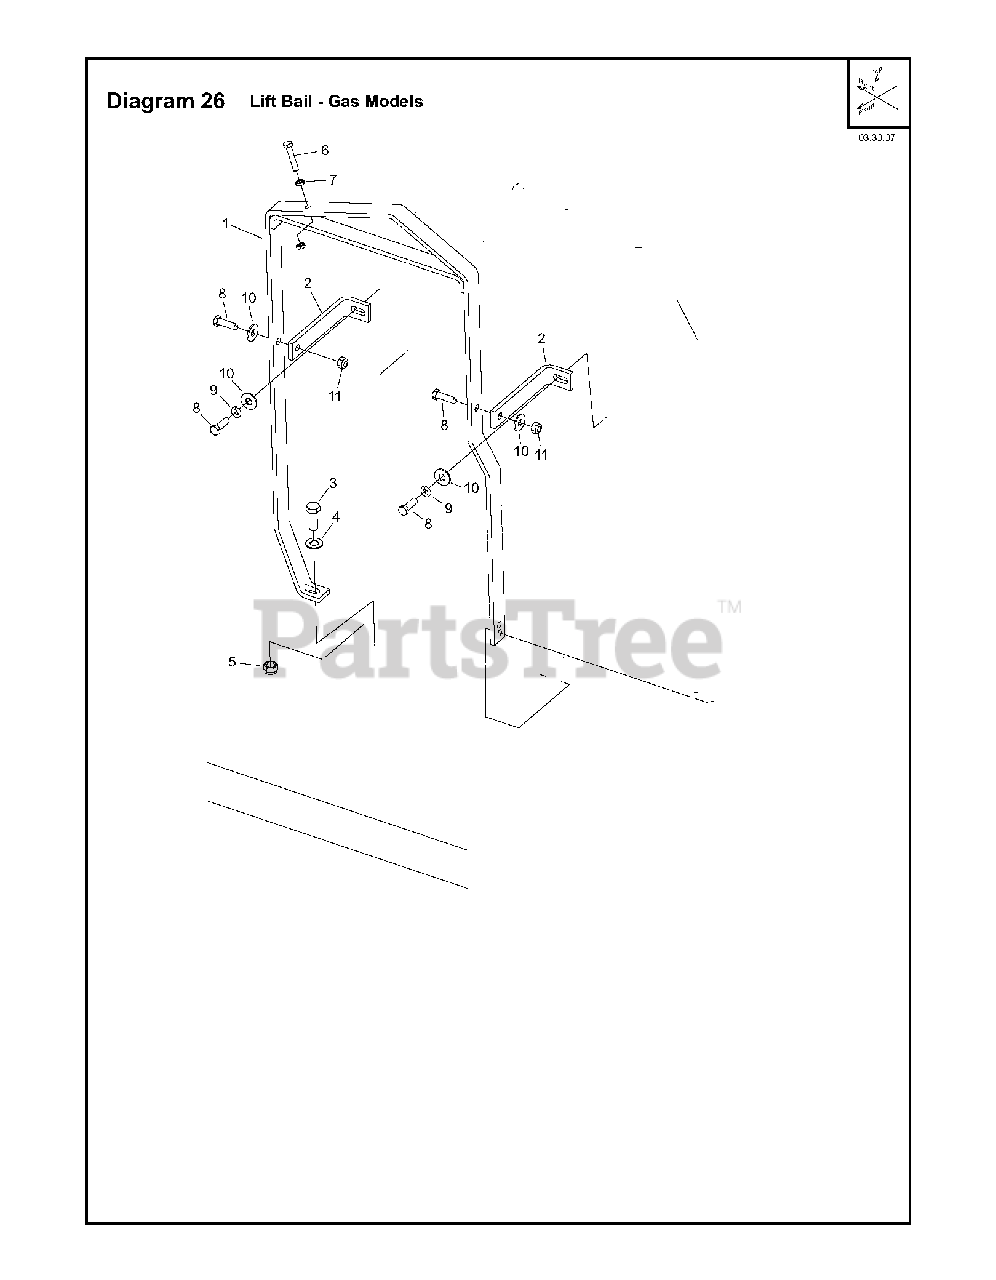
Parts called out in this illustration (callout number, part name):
1	LIFT FRAME (PAINTED)
2	BRACE. LIFT FRAME BLK
3	HHCS. M16 x 2 x 45 DIN931 Z/P
5	LOCKNUT. FIBER M16 x 2.0
6	HHCS. M10 x 1.5 x 50 DIN933 ZP
9	LOCKWASHER. SPLIT M12 DIN 127
11	LOCKNUT. FIBER M12 DIN 985 Z/P
